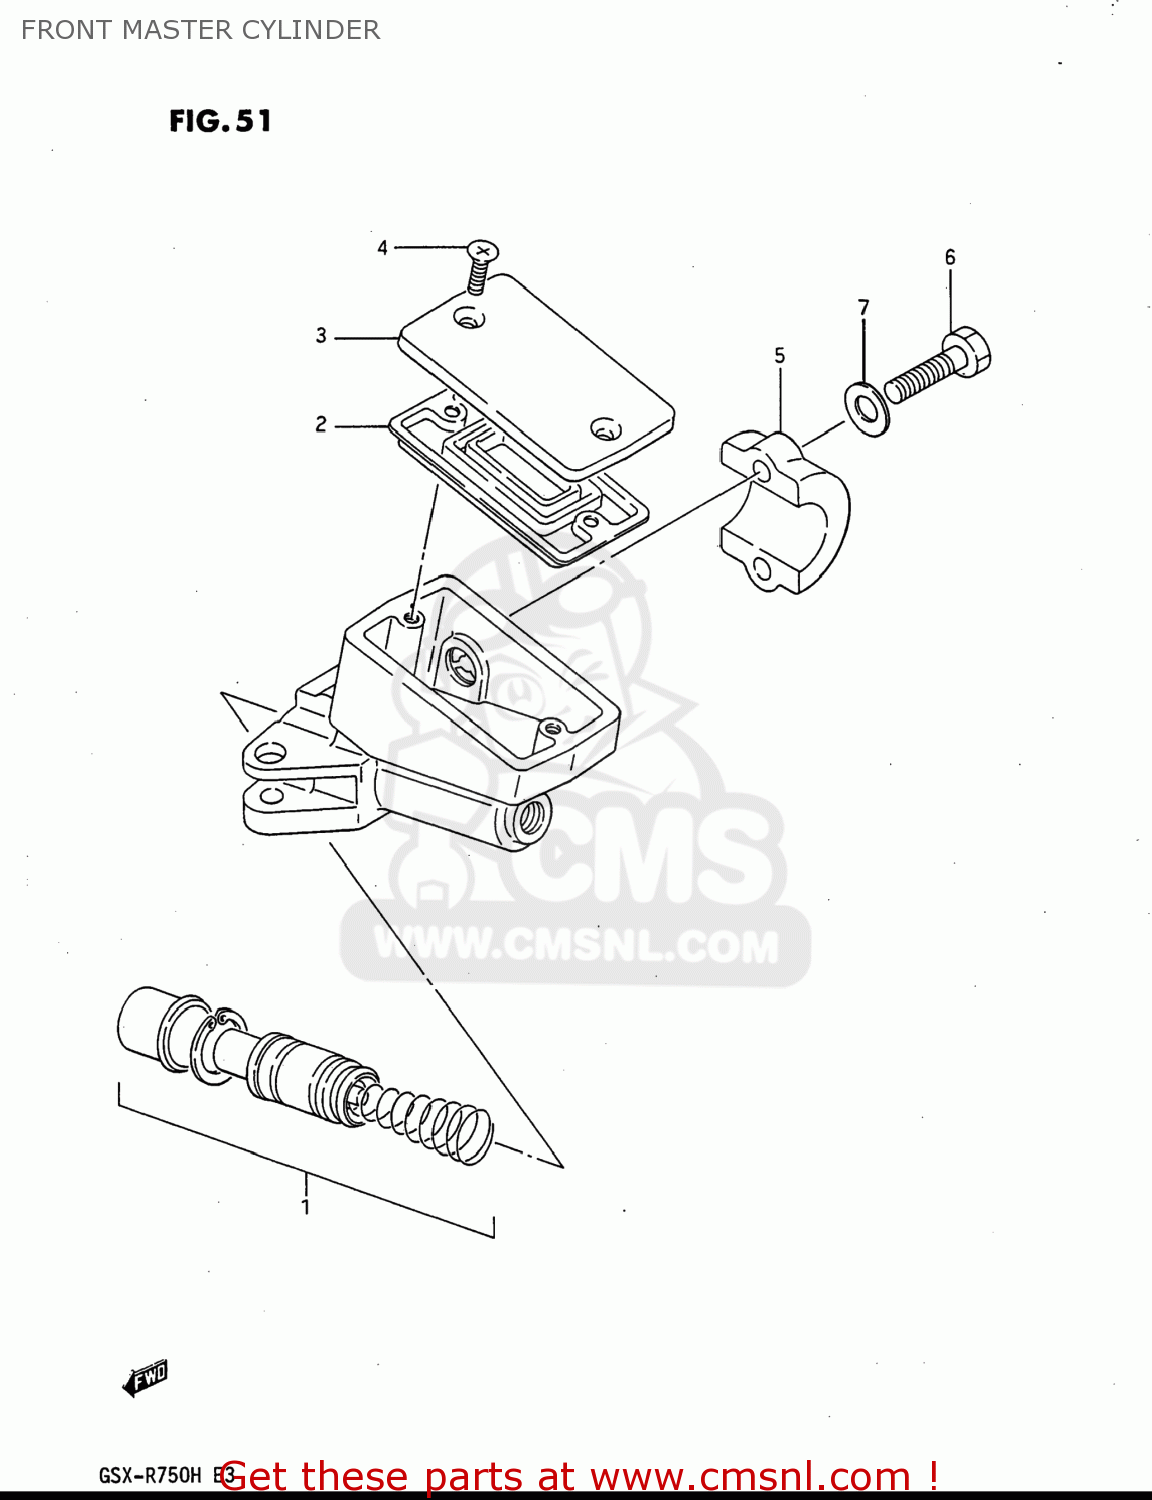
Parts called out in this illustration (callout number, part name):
1	PISTON & CUP SET
2	3
3	CAP
4	SCREW
5	HOLDER,MASTER CYLINDER
6	BOLT
7	WASHER
